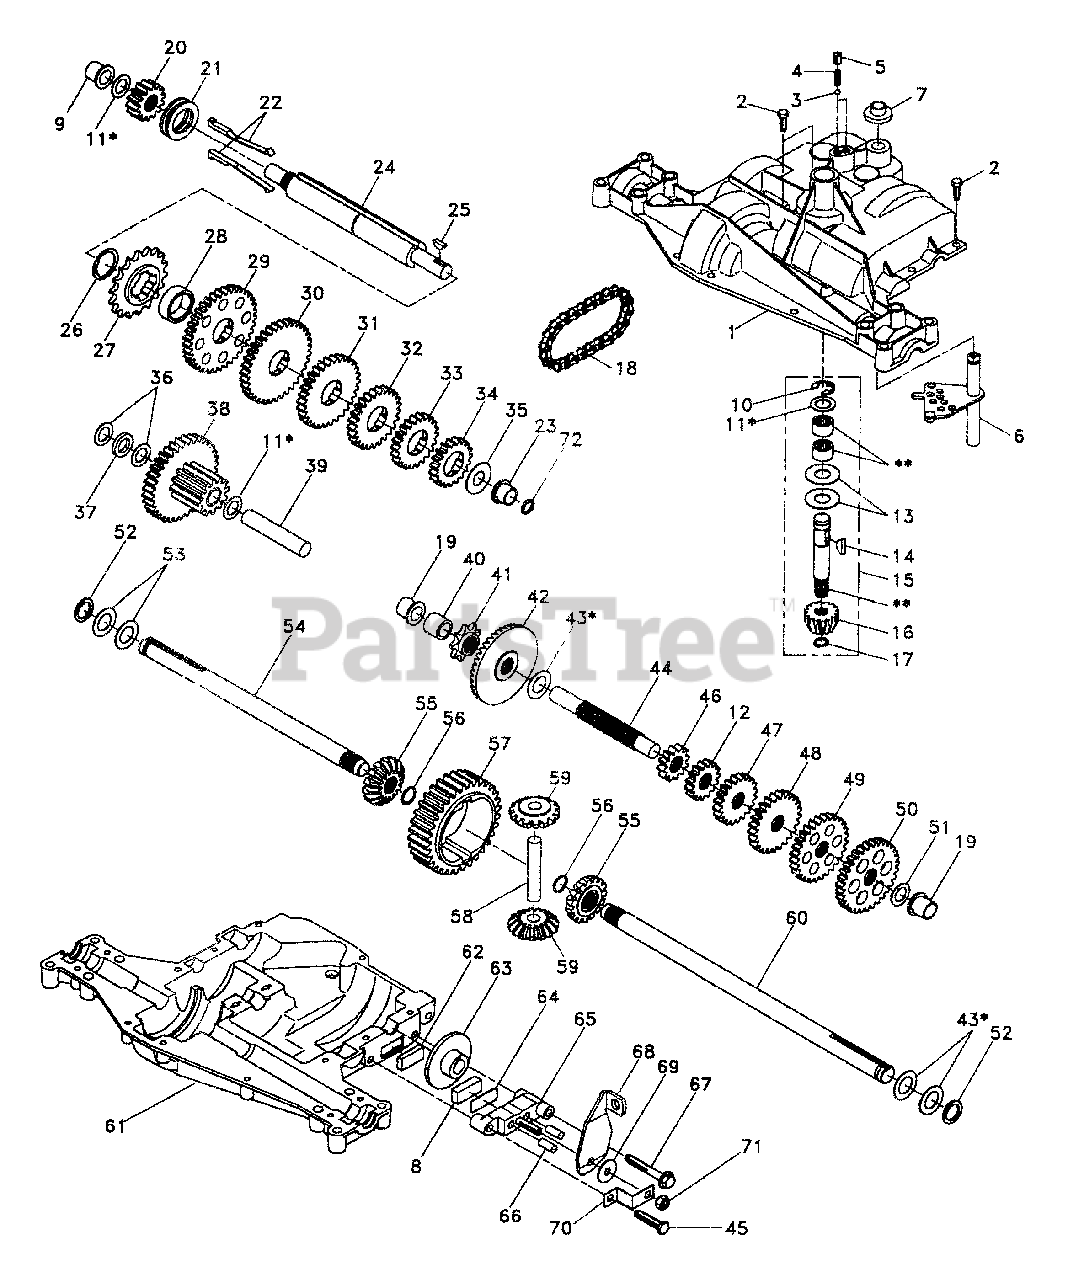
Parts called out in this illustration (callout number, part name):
1	Housing, Upper
2	Screw, Tapping, Large 1/4-20 x .734
3	Ball, Detent
4	Spring, Detent
5	Screw, Set
6	Kit, Shifter Assembly
7	Boot, Shifter
8	Puck, Friction
9	Bearing, Flange
10	Ring, Retaining
11	Assembly, Kit, Shim, .625 Shaft
12	Gear, Spur, 15 Teeth (2nd)
13	Washer, Plain .632 x 1.38 x .046
14	Key, Woodruff, #9
15	Assembly, Kit, Input Shaft
16	Pinion, Bevel, 14 Teeth
17	Ring, Retaining
18	Chain, 24 Pitches
19	Bearing, Flange
20	Gear, Spur, 14 Teeth
21	Collar, Clutch
22	Assembly, Kit, Clutch Keys
23	Bearing, Flange
24	Shaft, Intermediate
25	Key, Woodruff, #61
26	Ring, Retaining
27	Sprocket, 18 Teeth (Reverse)
29	Gear, Spur, 37 Teeth (1st)
30	Gear, Spur, 35 Teeth (2nd)
31	Gear, Spur, 30 Teeth (3rd)
32	Gear, Spur, 25 Teeth (4th)
33	Gear, Spur, 22 Teeth (5th)
34	Gear, Spur, 19 Teeth (6th)
35	Washer, Plain .640 x 1.37 x .061
36	Washer, Plain .632 x 1.00 x .026
37	Spacer .630 x 1.00 x .169
38	Assembly, Gear, Combination, 12 Teeth and 35 Teeth
39	Shaft, Idler
40	Spacer .633 x .87 x .755
41	Sprocket, 9 Teeth (Reverse)
42	Gear, Bevel, 42 Teeth
43	Assembly, Kit, Shim, .750 Shaft
44	Shaft, Drive
45	Screw, Tapping, Large 5/16-18 x 1.44
46	Gear, Spur, 12 Teeth (1st)
47	Gear, Spur, 20 Teeth (3rd)
48	Gear, Spur, 25 Teeth (4th)
49	Gear, Spur, 28 Teeth (5th)
50	Gear, Spur, 31 Teeth (6th)
51	Washer, Plain .632 x 1.00 x .060
52	Washer, Neoprene
53	Washer, Plain .758 x 1.25 x .031
54	Axle, L.H.
55	Gear, Miter, 15 Teeth
56	Ring, Retaining
57	Gear, Spur, 32 Teeth
58	Shaft, Cross
59	Gear, Miter, 15 Teeth
60	Axle, R.H.
61	Housing, Lower
62	Puck, Friction
63	Disc, Brake
65	Jaw, Brake
66	Pin, Dowel
67	Screw, Tapping 5/16-18 x 2.25
68	Lever, Actuating
69	Washer, Plain .321 x 1.00 x .055
70	Bracket, Anti-Rotation
71	Locknut 5/16-24
73	Grease
